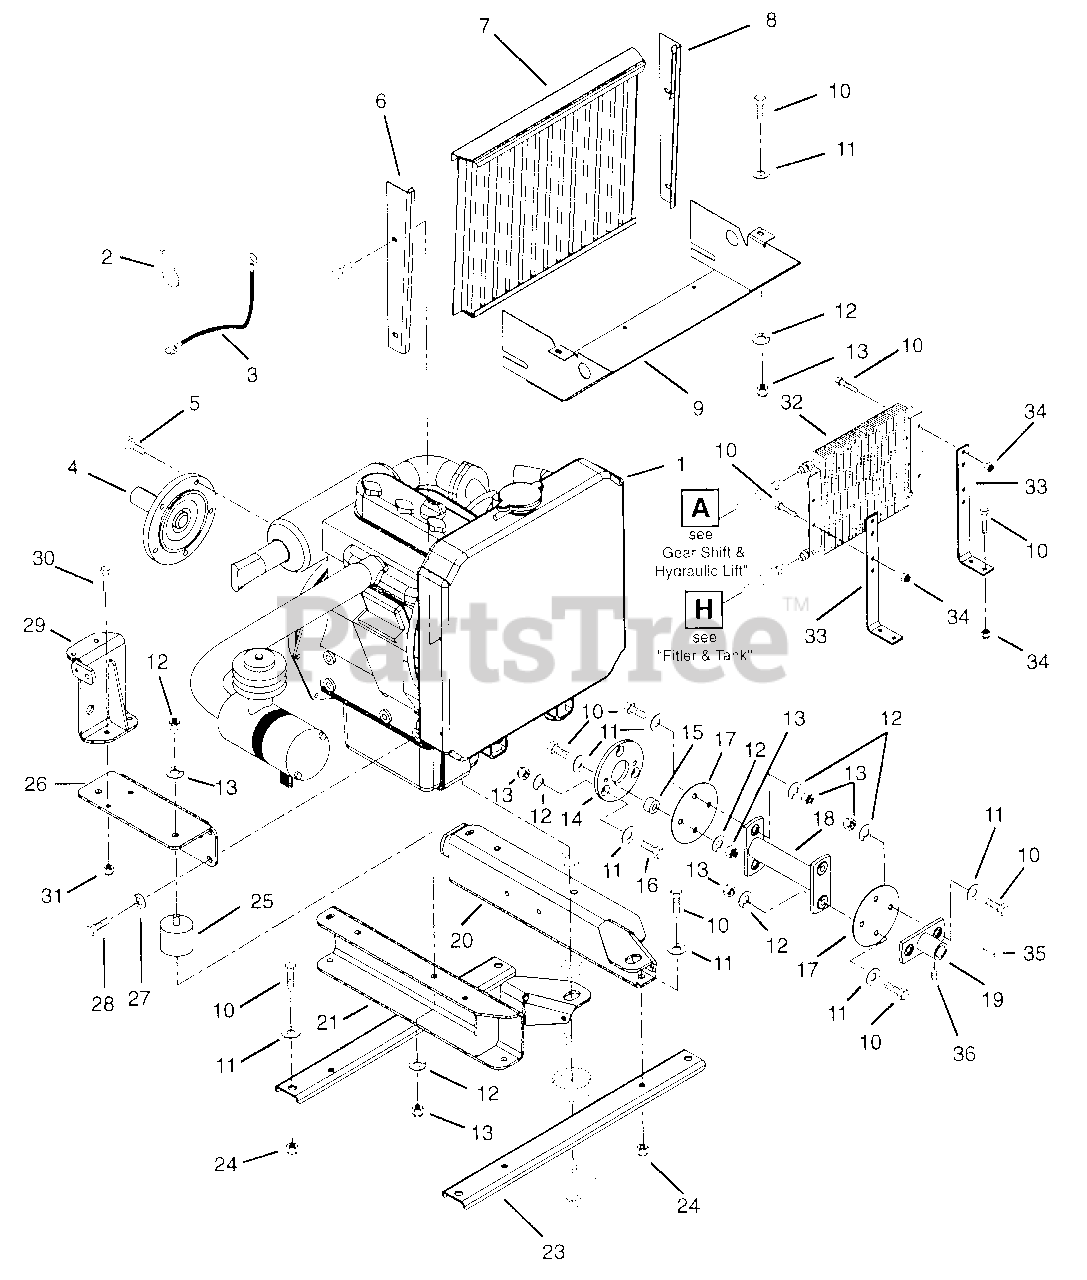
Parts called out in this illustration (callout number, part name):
1	Engine 21 HP Kubota Diesel D722B-1
2	Tie Wrap, Black
3	Ground Strap
4	Stud Shaft Weldment, Clutch
5	Screw, M8 x 1.25 x 20mm
6	Weldment, Screen Support, Right Hand
7	Grille, Radiator
8	Weldment, Screen Support, Left Hand
9	Shield, Bottom Air Intake
10	Bolt-Hex .375-16 x 1.00 Grade 5
11	Washer-Flat-Steel .38 x .875 x .083
12	Washer-Lock .375 x .094
13	Nut-Hex .375-16 Grade 2
14	Plate, Adapter
15	Spacer, .406 I.D. x .88 O.D. x .38 Long
16	Bolt-Hex .38-16 x 1.00
17	Flex Coupling Disc
18	Weldment, Transmission Drive Shaft
19	Weldment, Transmission Coupling
20	Weldment, Lower Left Hand Engine Mount
21	Engine Mount, Lower Right Hand Kubota
22	Bracket, Engine Mount
23	Bracket, Engine Mount
24	Nut-Locking-Nylon .375-16 Grade 2
25	Vibration Isolator, Kubota
26	Weldment, Upper Right Hand Kubota EngineMount
27	Washer-Lock Metric 10MM
28	Screw, Hex head 10MM-1.25 x 20
29	Weldment, Diesel Fuel Filter Mount
30	Bolt-Hex .31-18 x 1.00 Grade 5
31	Nut-Locking .312-18
32	Cooler, Oil
33	Bracket, Oil Cooler Mount
34	Nut-Lock-Nylon .250-20 Grade 2
35	Key-Woodruff .125 x .625 x .250
36	Screw-Set .32-18 x .38 Socket Head Cup Point Nylon
